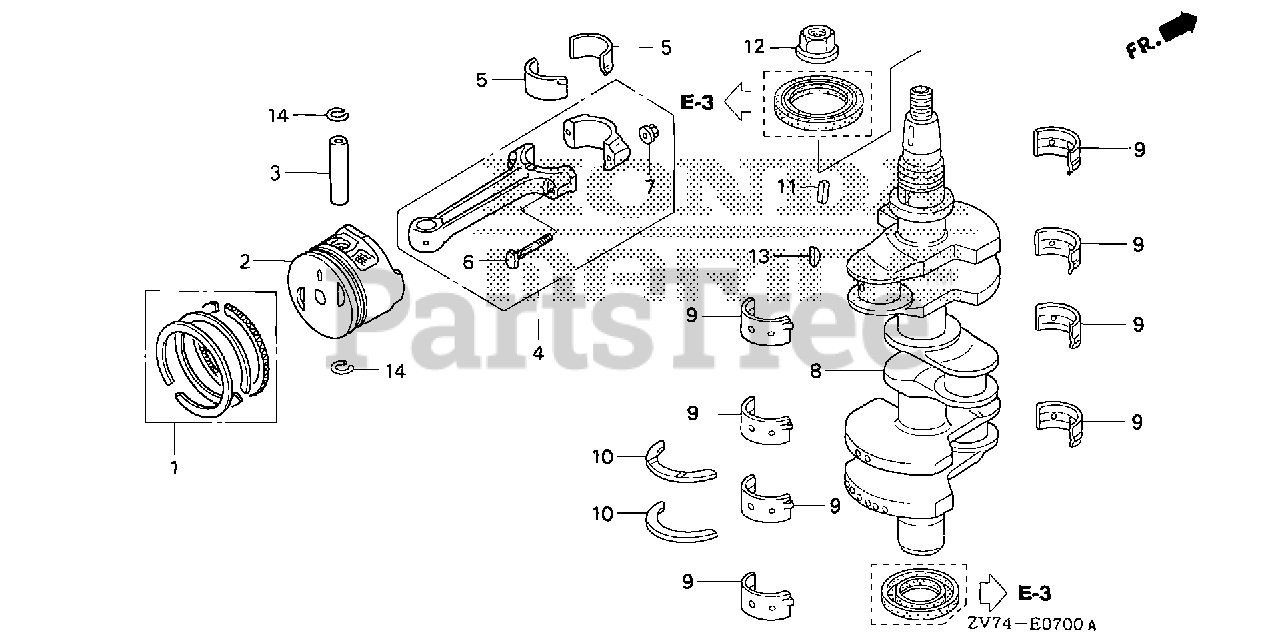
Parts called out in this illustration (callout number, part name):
1	RING SET, PISTON (STD)
3	PIN, PISTON
4	ROD SET, CONNECTING
5	BEARING A, CONNECTING ROD (BROWN)
5	BEARING B, CONNECTING ROD (GREEN)
5	BEARING C, CONNECTING ROD (YELLOW)
5	BEARING D, CONNECTING ROD (PINK)
5	BEARING E, CONNECTING ROD (RED)
6	BOLT, CONNECTING ROD
7	NUT, CONNECTING ROD
8	CRANKSHAFT
9	BEARING A, MAIN (17MM) (GREEN)
9	BEARING B, MAIN (17MM) (YELLOW)
9	BEARING C, MAIN (17MM) (PINK)
9	BEARING D, MAIN (17MM) (RED)
10	WASHER, THRUST
11	KEY, SPECIAL WOODRUFF (25X18)
12	NUT, SPECIAL (18MM)
13	KEY, SPECIAL (16X15)
14	CLIP, PISTON PIN (16MM)
